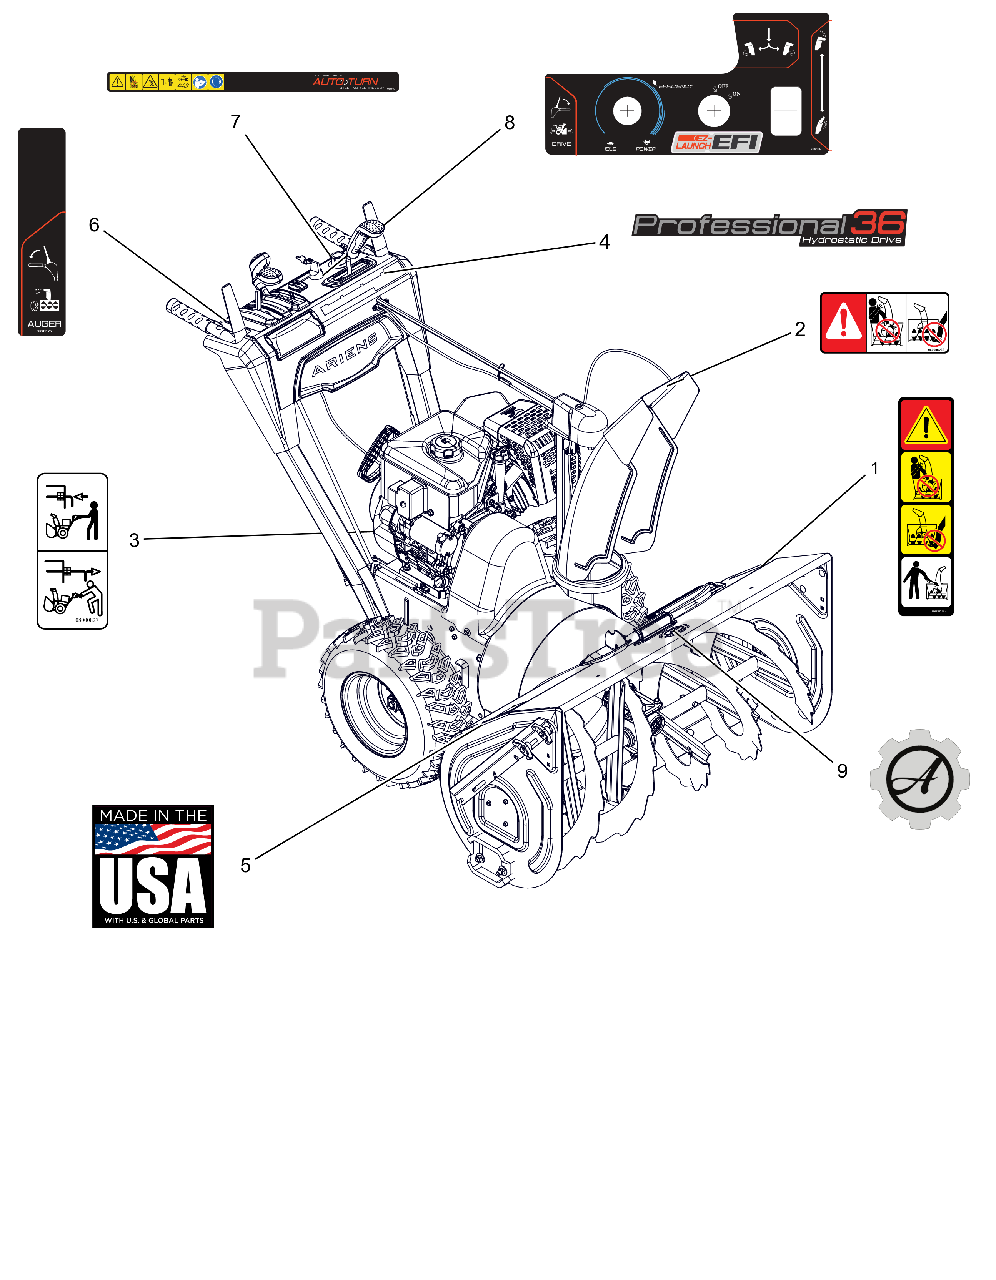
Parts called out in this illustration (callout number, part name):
1	DECAL, DANGER - ROTATING PARTS
2	DECAL, DANGER
3	DECAL, BYPASS
4	DECAL, DASH - PRO HYDRO 36
5	DECAL, MADE IN USA
6	DECAL,CONTROL-RH CONTROL
7	DECAL,DASH - SAFETY/EFI
8	DECAL, CONTROL - QT EFI W/GEL
9	DECAL, ARIENS-GEAR BADGE -THK
